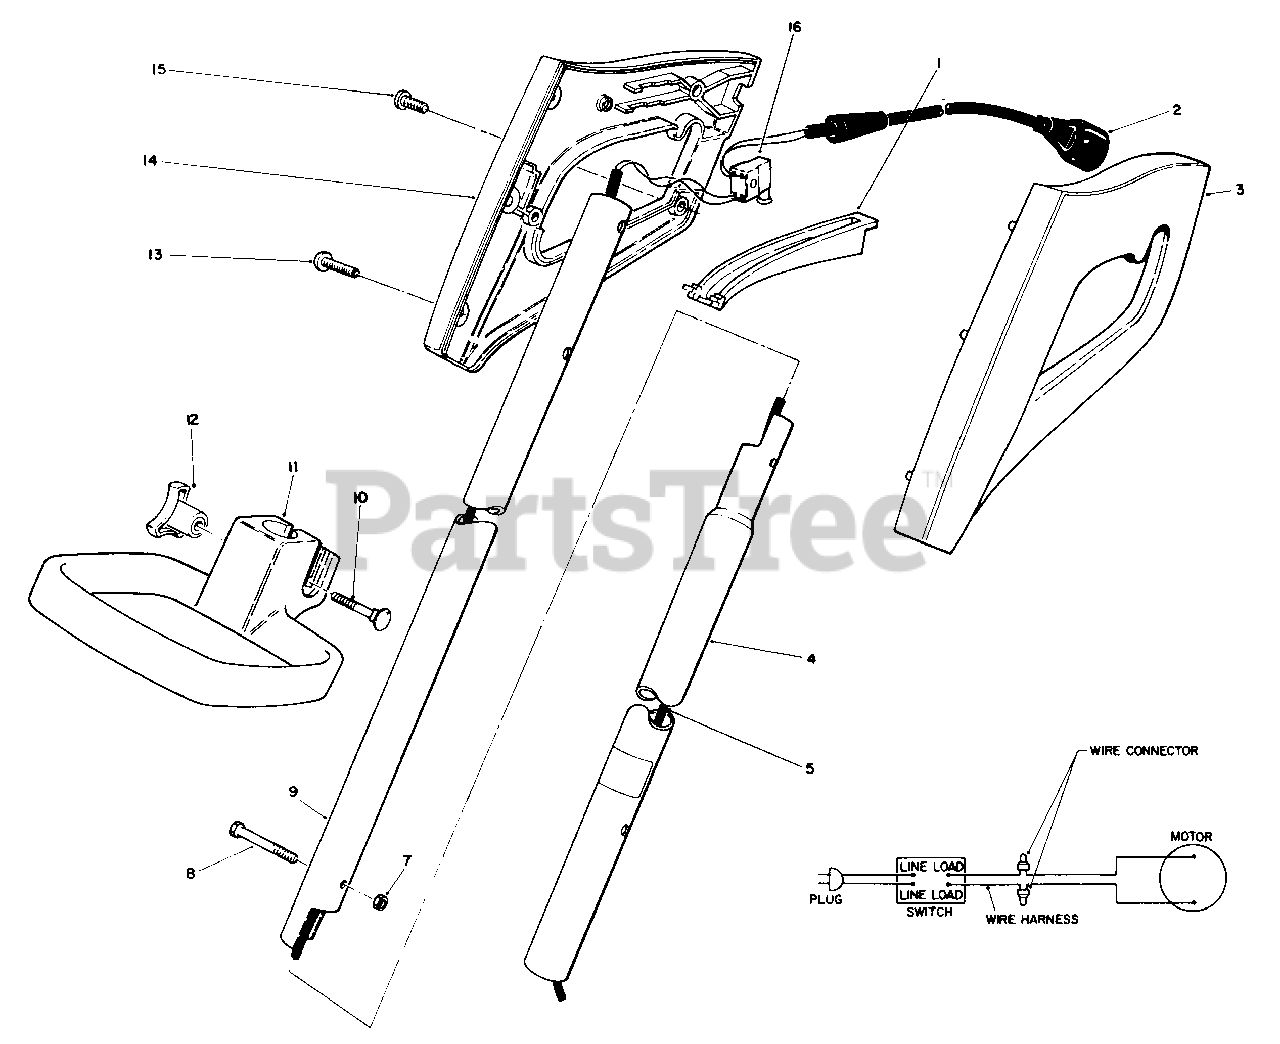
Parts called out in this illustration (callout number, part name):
1	Bar-Switch
2	Cord-Power
3	Grip-L.H.
4	Tube-Lower Extension
5	Wire Harness
7	Nut-Lock
8	Screw-Hex. Hd. Machine
9	Tube-Upper Extension
10	Bolt-Carriage
11	Handle-Adjustment
12	Knob-Adjustable
13	Screw-Thread Forming
14	Grip-R.H.
15	Screw-Thread Forming
16	Switch-Single Speed
